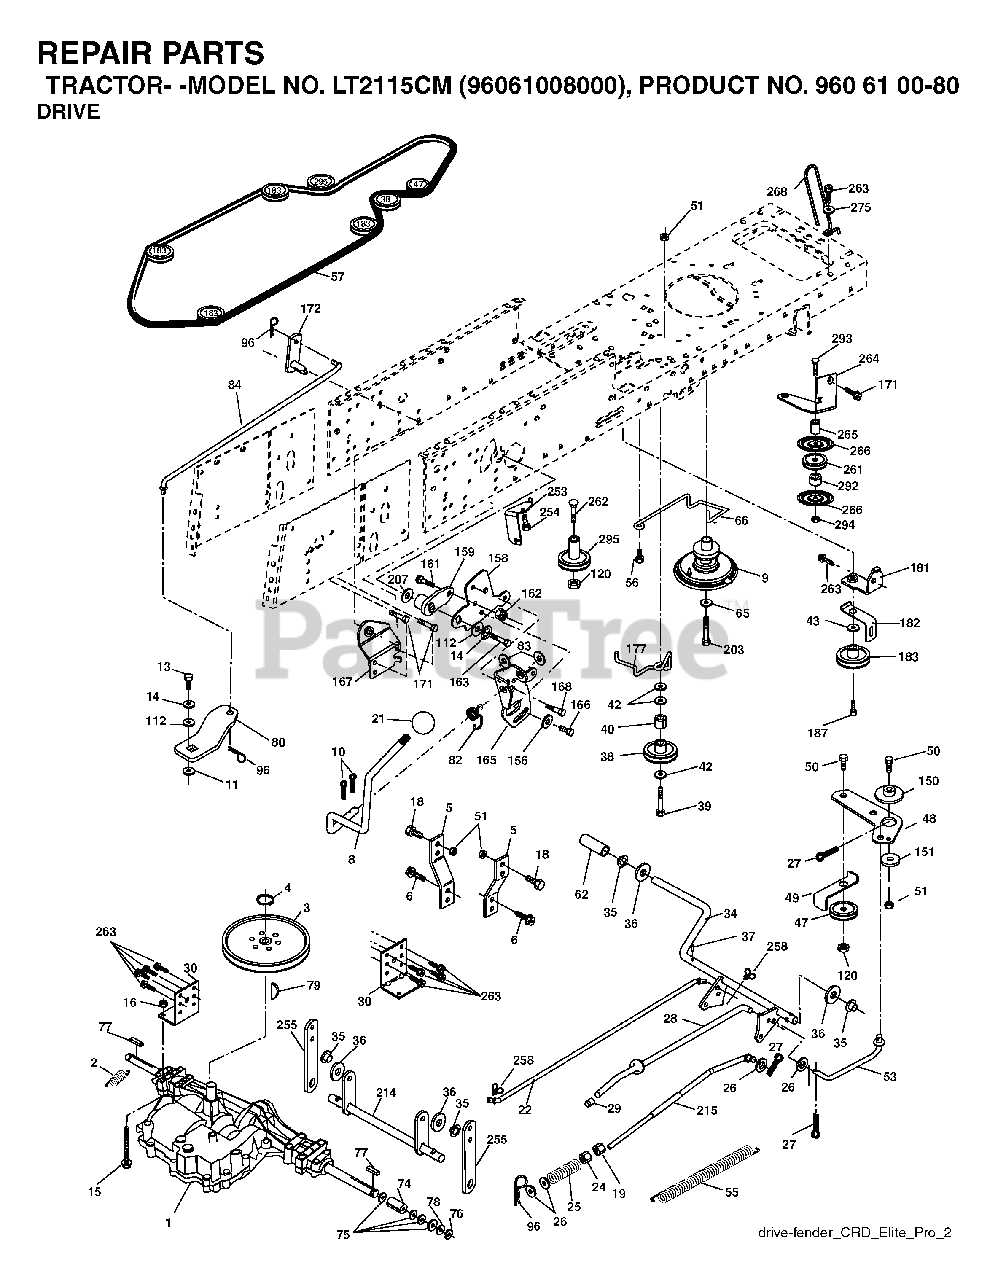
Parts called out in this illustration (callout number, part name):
2	SPRING,BRAKE RETURN
4	RETAINING RING LT
5	STRAP TORQUE
6	SCREW 5/16"
8	ROD SHIFT FENDER ADJUST LT
10	PIN COTTER
11	WASH-SHFT PLT LT
13	BOLT 1/4-28X3/4
14	LOCKWASHER
15	BOLT HEX 5/16-18 GR 5
16	NUT.71038.31-18.HEX.NYLOCK
18	BOLT
19	NUT
21	KNOB.DUCKHEAD.1/2
24	NUT
25	SPRING ROD LT
27	COTTER PIN
28	ROD, PARKING BRAKE
29	PLUNGER CAP
30	BRKT, MOUNT TRNSAXLE
34	SHAFT, FOOT PEDAL
35	BEARING.NYLON
36	WASHER LT
37	DRIVE PIN
38	PULLEY.FLAT
42	WASHER
43	WASHER T
47	IDLER PULLEY
48	BELLCRANK, CLUTCH
49	RETAIN BELT
50	BOLT.3/8-16X1.50
51	LOCKNUT
53	LINK.CLUTCH.7.66.2005
55	SPRING, RETURN LT
56	SCREW.3/8-16
57	V-BELT.KEV.111"
62	COVER, PEDAL
65	LOCKWASHER
66	KEEPER BELT ENGINE
74	SPACER AXLE
76	E-RING LT
77	SQUARE KEY
80	ARM SHIFT
82	SHIFT SPRING
83	WASHER
96	RETAINER M
112	WASHER LT
120	NUT LOCK FLG 3/8-16 UNC
150	BUSHING.BELLCRANK.GRD.DR
151	WASHER 12/32X2X10GA
156	WASHER.SRRTD.5/16
158	BRACKET
159	HUB.SHIFT
161	BOLT
162	NUT.CROWNLOCK.1/4
163	BOLT
165	RP BRACKET
166	SCREW
167	BRACKET
168	BOLT.SHOULDER.5/16-18X
171	SCREW LT
187	BOLT.5/16-18X1.25
207	WASHER NYL
254	SCREW 3/8-16X1
258	CLIP RETAINER
261	FLAT IDLER PULLEY
263	SCREW, 3/8-16X3/4
265	SPACER IDLER
275	WASHER
294	NUT, HEX 3/8-16
295	PULLEY IDLER COMPOSITE
